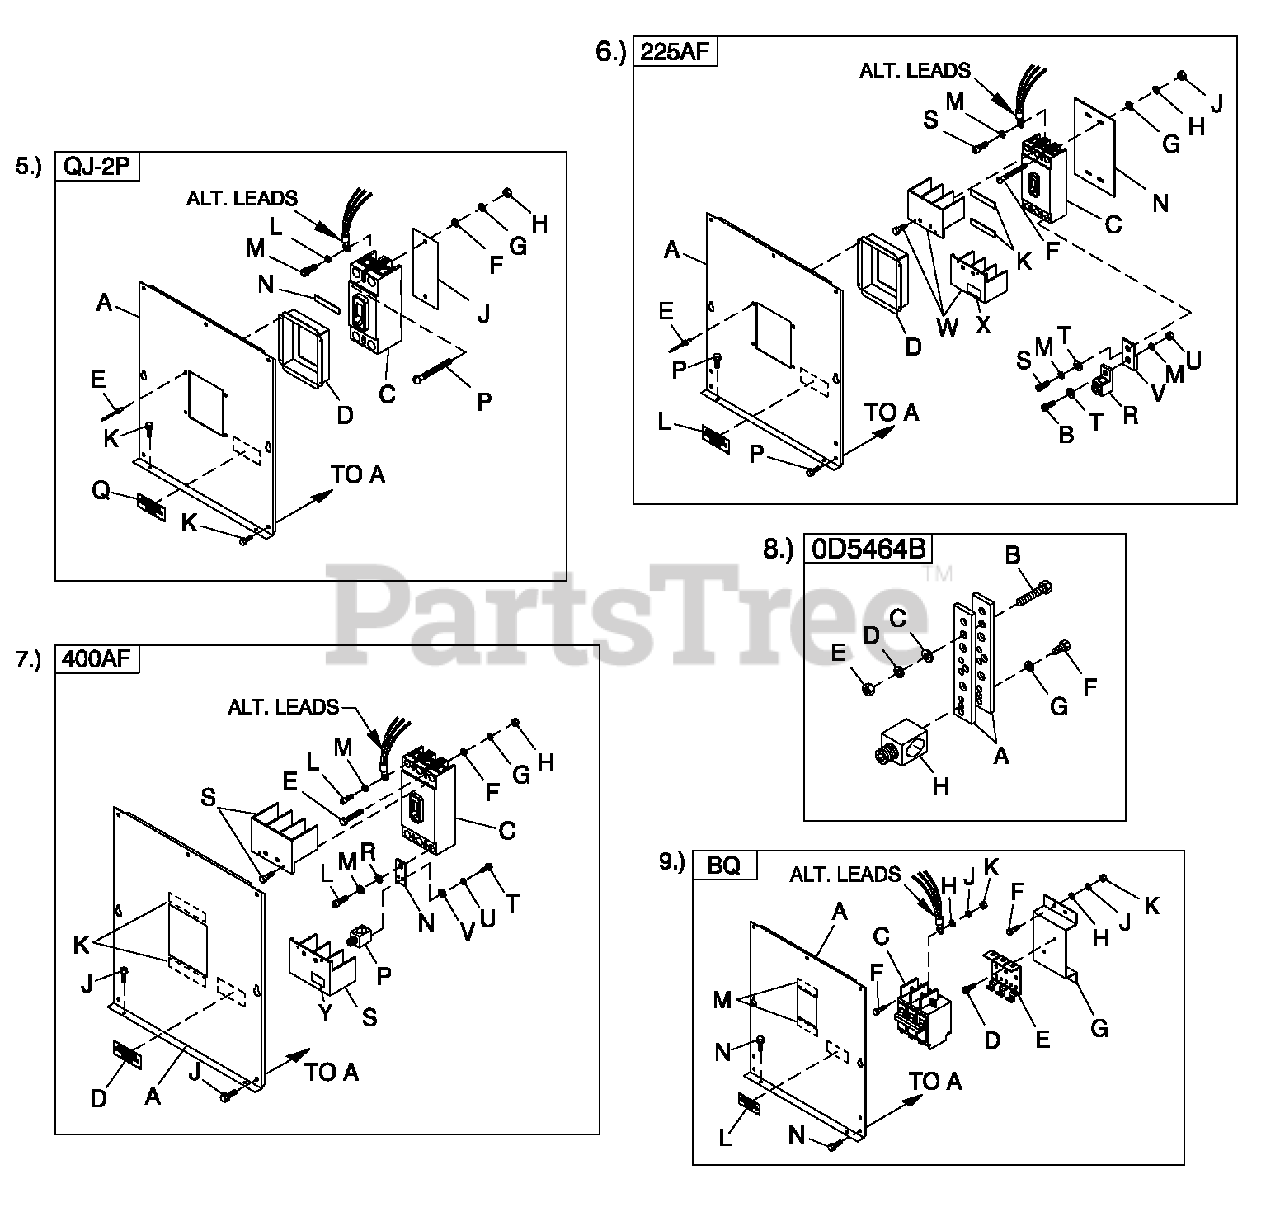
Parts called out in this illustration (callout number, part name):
A	COVER QJ 2P FRMCB
C	CB 0225A 240V 2P S QJ22
D	COVER QJ 2P CB DISH
E	RIVET POP .125 X .275 SS
F	WASHERFLAT 1/4-M6 ZINC
G	WASHERLOCK M6-1/4
H	NUT HEX 1/4-20 STEEL
J	INSULCB2PQJ
K	SCREW THF M6-1 X 16 N WAZ/JS
L	WASHER LOCK 3/8
M	SCREW SHC 3/8-16 X 3/4 G8.8 NZ
N	TAPE ELEC 1/2 FOAM (AS REQ'D)
P	SCREW RHM 1/4-20X3
Q	DECAL CUSTOMER CONNECT INSIDE
A	COVER CB C2-C4 (225AF)
B	SCREW SHC M8-1.25 X 25 G12.9
C	CIRCUIT BREAKERS 200A FRAME (3P)
D	COVER CB DISH 225AF (3P)
F	SCREW RHM #8-32X3-1/4
G	WASHER FLAT #8 ZINC
H	WASHER LOCK #8-M4
J	NUT HEX #8-32 STEEL
K	TAPE ELEC 1/2 FOAM
L	DECAL CUSTOMER CONNECT INSIDE
M	WASHERLOCK M8-5/16
N	INSULATOR CB225AF(3P)
P	SCREW THF M6-1 X 16 N WAZ/JS
R	LUG SLDLSS 300 MCM-6 AL/CU
S	SCREW SHC M8-1.25X 20G8
T	WASHERFLAT 5/16-M8ZINC
U	NUT HEX M8-1.25 G8 CLEAR ZINC
V	BUS BAR 200A LUG ADAPTOR
W	TERMINAL COVER CB
X	DECALTERMINALSHOCK HZD BI
A	COVER CB C2-C4 400AF
C	CIRCUIT BREAKERS 400A FRAME
D	DECAL CUSTOMER CONNECT INSIDE
E	SCREW RHM 10-32X4
F	WASHER FLAT #10 ZINC
G	WASHER LOCK #10
H	NUT HEX #10-32 STEEL
J	SCREW THF M6-1 X 16 N WAZ/JS
L	SCREW SHC M10-1.5X25G12.9
M	WASHERLOCK M10
N	BUS BAR CB ADAPTER 225-400 A
P	LUG SLDLSS 600/250-1/0 X 1/4-28
S	TERM COVER CB
T	SCREW HHC 1/4-28 X 1/2 G5
U	WASHERLOCK M6-1/4
V	WASHERFLAT 1/4-M6 ZINC
W	SCREW SHC M10-1.5X25G12.9
X	WASHERLOCK M10
Y	DECAL TERMINALSHOCK HZD BI
A	BUS BAR NEUTRAL BLOCK 390
B	SCREW HHC M8-1.25 X 45 G8.8 FT
C	WASHER FLAT 5/16-M8 ZINC
D	WASHERLOCK M8-5/16
E	NUT HEX M8-1.25G8YEL CHR
F	SCREW HHC 1/4-28 X 3/4 G5
G	WASHER LOCK 1/4-M6SS
H	LUG SLDLSS 600/250-1/0 X 1/4-28
A	COVER BQ CIR BREAKER CPL 3P
C	CB0125A2P 240V SBQ2 LL
D	SCREW PHTT M4-0.7X 10 ZYC
E	BRKT CB MTG BACK
F	SCREW RHM #10-32X3/4
G	BRKT BQCB STANDOFF
H	WASHER FLAT #10 ZINC
J	WASHER LOCK #10
K	NUT HEX #10-32 STEEL
M	TAPE ELEC 1/2 FOAM
N	SCREW THF M6-1 X 16 N WA Z/JS
